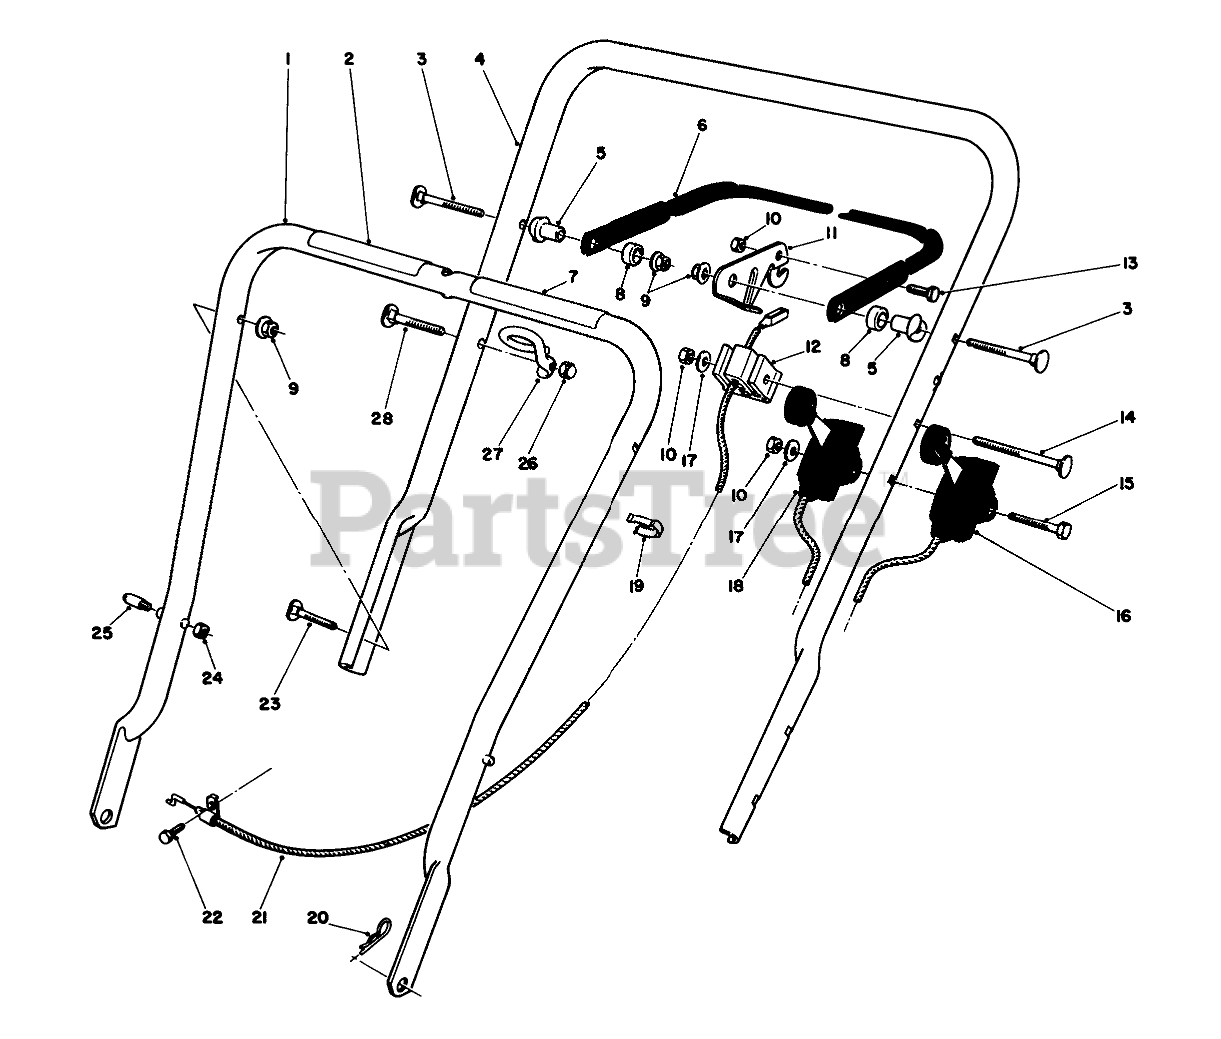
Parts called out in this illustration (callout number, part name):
1	Lower Handle Assembly (Incl. Ref. #2 & 7)
2	DECAL - INSTRUCTIONS
3	5/16-18 X 2 HNDLE SCREW
4	UPPER HANDLE
5	SPACER-SUPPORT
6	CONTROL BAR PROMO
7	DANGER DECAL
8	SPACER-NYLON
9	NUT-LOCK, NI
10	NUT-LOCK, NI
11	Lever-Control
12	SUPPORT-CABLE
13	SCREW-HH
14	HANDLE SCREW
15	SCREW-HH
16	TRACTION CABLE
17	WASHER-FLAT
18	SERVICE THROTTLE CONTRO
19	BOWDEN CLIP
20	PIN-COTTER, HAIR
21	BRAKE CABLE
22	SCREW-HH
23	SCREW
24	NUT-LOCK, NI
25	HANDLE PIN
26	NUT-CAP
27	Guide
28	HANDLE SCREW
